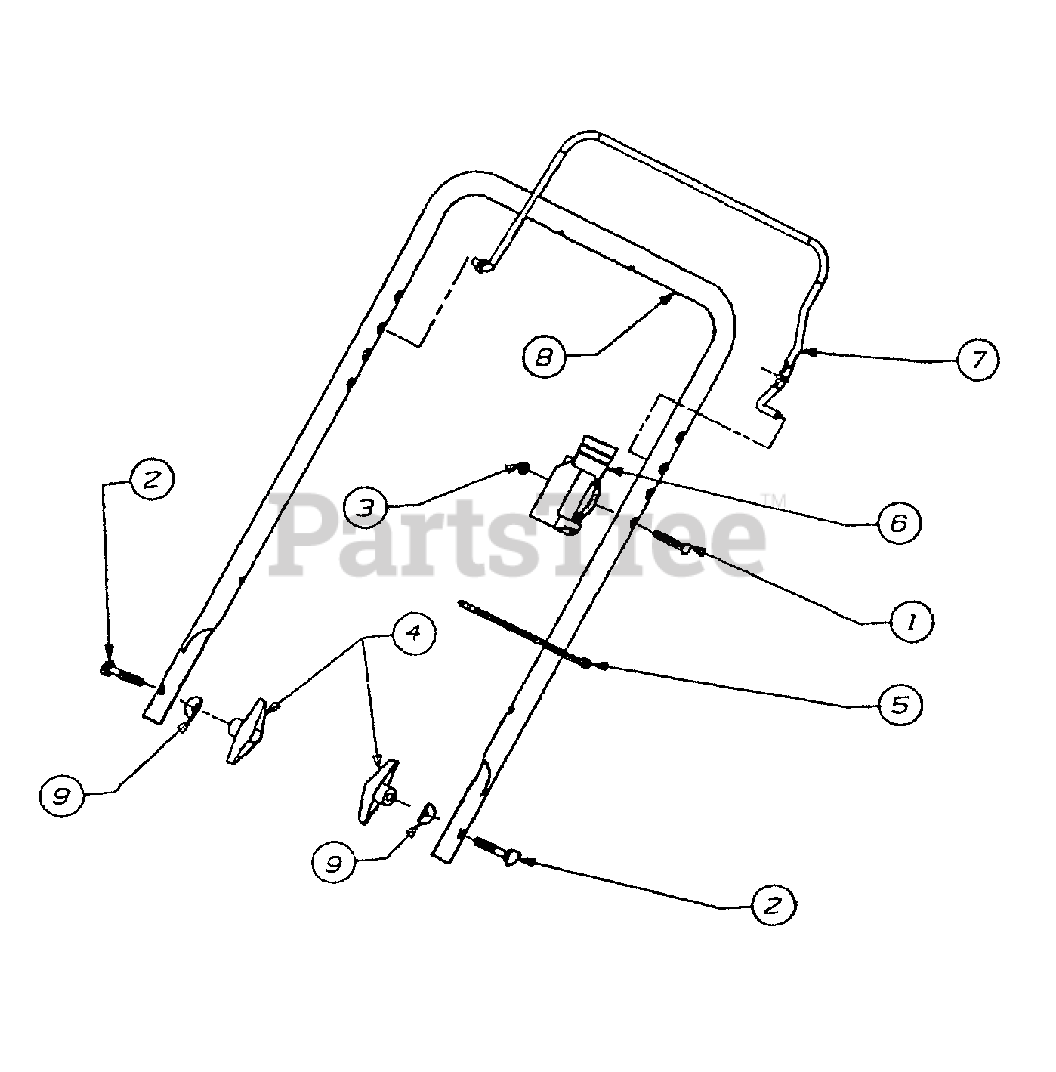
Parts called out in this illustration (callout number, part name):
1	Oval C-Sunk Screw
2	Carriage Bolt
4	Handle Knob
5	Cable Tie
6	Control Lever
